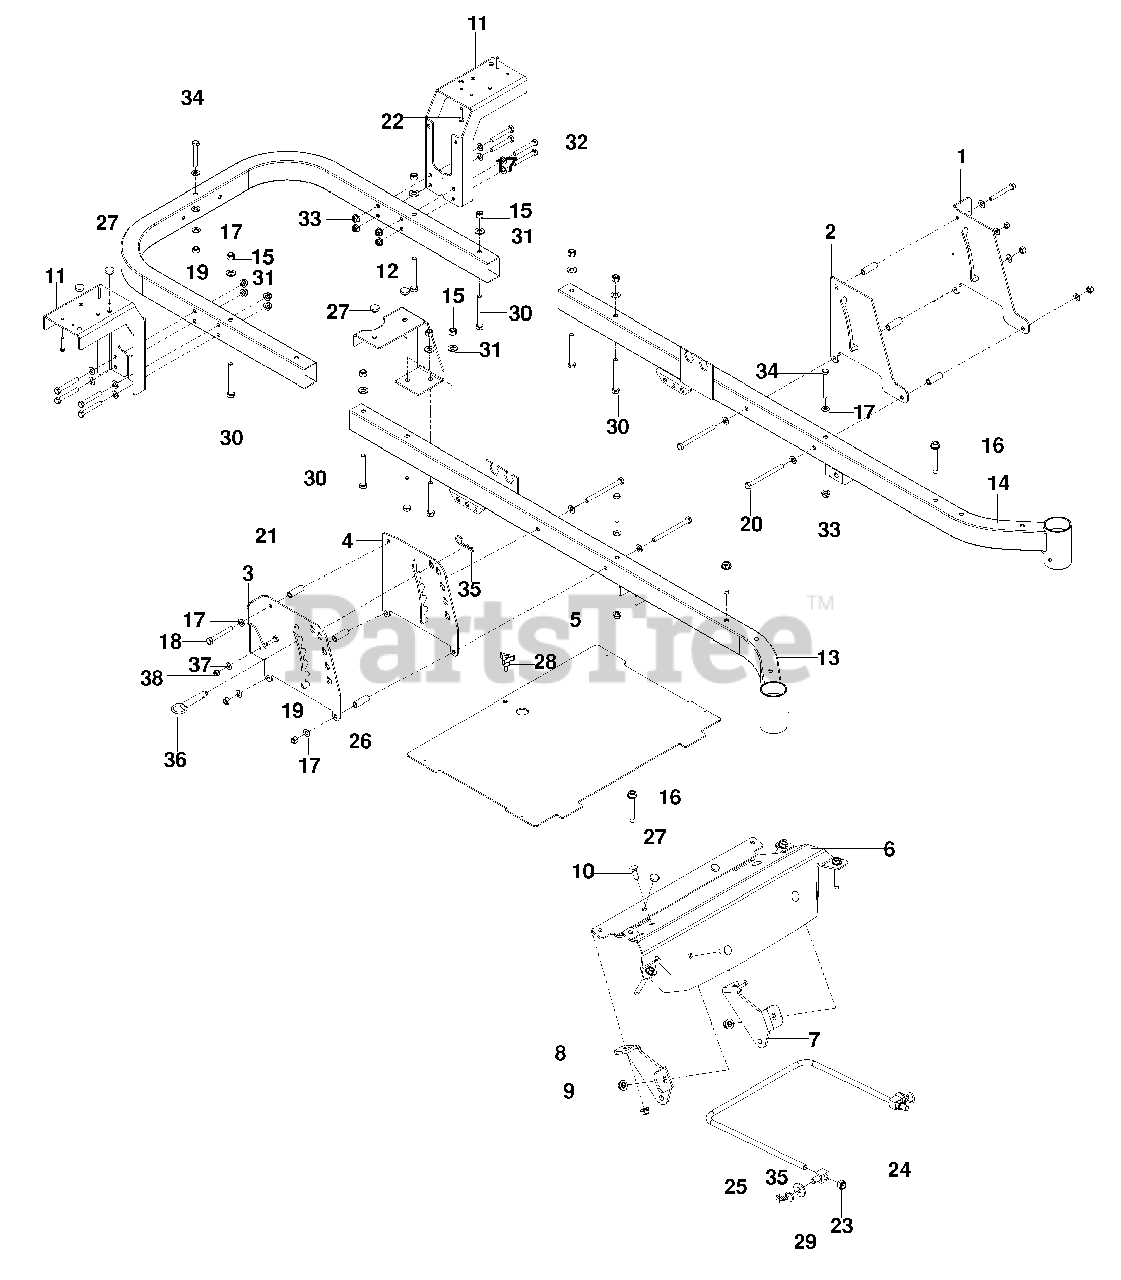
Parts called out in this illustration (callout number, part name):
1	PLATE, OUTER BRAKE
2	PLATE, BRAKE LATCH
3	PLATE, DECK HEIGHT
4	PLATE, DECK HEIGHT
5	FOOT PLATE w/DECALS
7	MOUNT, STRUT, RT, BLK
8	MOUNT, STRUT, LT, BLK
9	NUT 3/8-16 HEX FLG NYLOC
10	RHSNB 3/8-16 x 1
11	SUPPORT, FENDER
12	SUPPORT, TANK
13	FRAME, FRONT RT
14	FRAME, FRONT LT
15	NUT 3/8-16 HEX NYLOC
16	BOLT 3/8-16 x 25/8 THD FRM
17	WASHER 5/16 SAE FLAT
18	HCS 5/16-18 x 2 1/2
19	NUT 5/16-18 HEX NYLOC
20	HCS 5/16-18 x 4
21	HCS 1/4-20 x 1
22	SCREW 10-12 x 1 1/4 WSH HD
23	NUT 7/16-14 HEX NYLOC
25	LINK, FRONT SUSPENSION
26	SPACER 1/2 OD x 1 1/2
27	GROMMET, BUMPER
28	KNOB w/STUD
29	WASHER 1/2 FLAT
30	HCS 3/8-16 x 3
31	WASHER 3/8 SAE FLT
32	HCS 5/16-18 x 2 1/4
33	NUT 5/16-18 FLANGE NYLOC
34	HCS 5/16-18 x 2 3/4
35	#4 HAIRPIN
37	WASHER 1/4 FLAT SAE
38	NUT 1/4-20 HEX NYLOC
